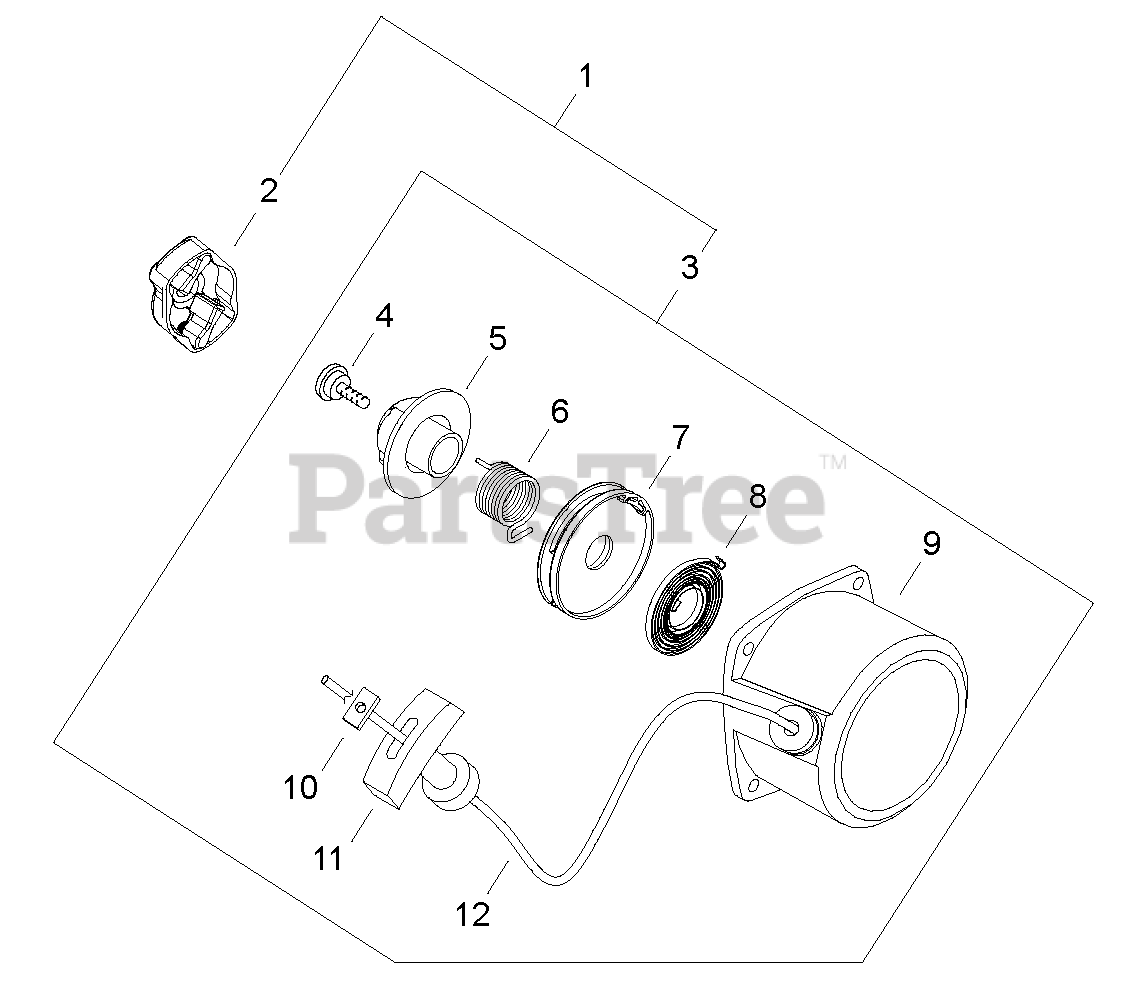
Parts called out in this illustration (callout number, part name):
1	STARTER KIT, EASY-TO-PULL
2	PULLEY, STARTER
3	STARTER ASSY, RECOIL
4	SCREW 5
5	CAM
6	SPRING, COIL
7	REEL, ROPE
8	SPRING, RECOIL
9	CASE, RECOIL STARTER
10	RETAINER, ROPE
11	GRIP, STARTER
12	ROPE, STARTER
